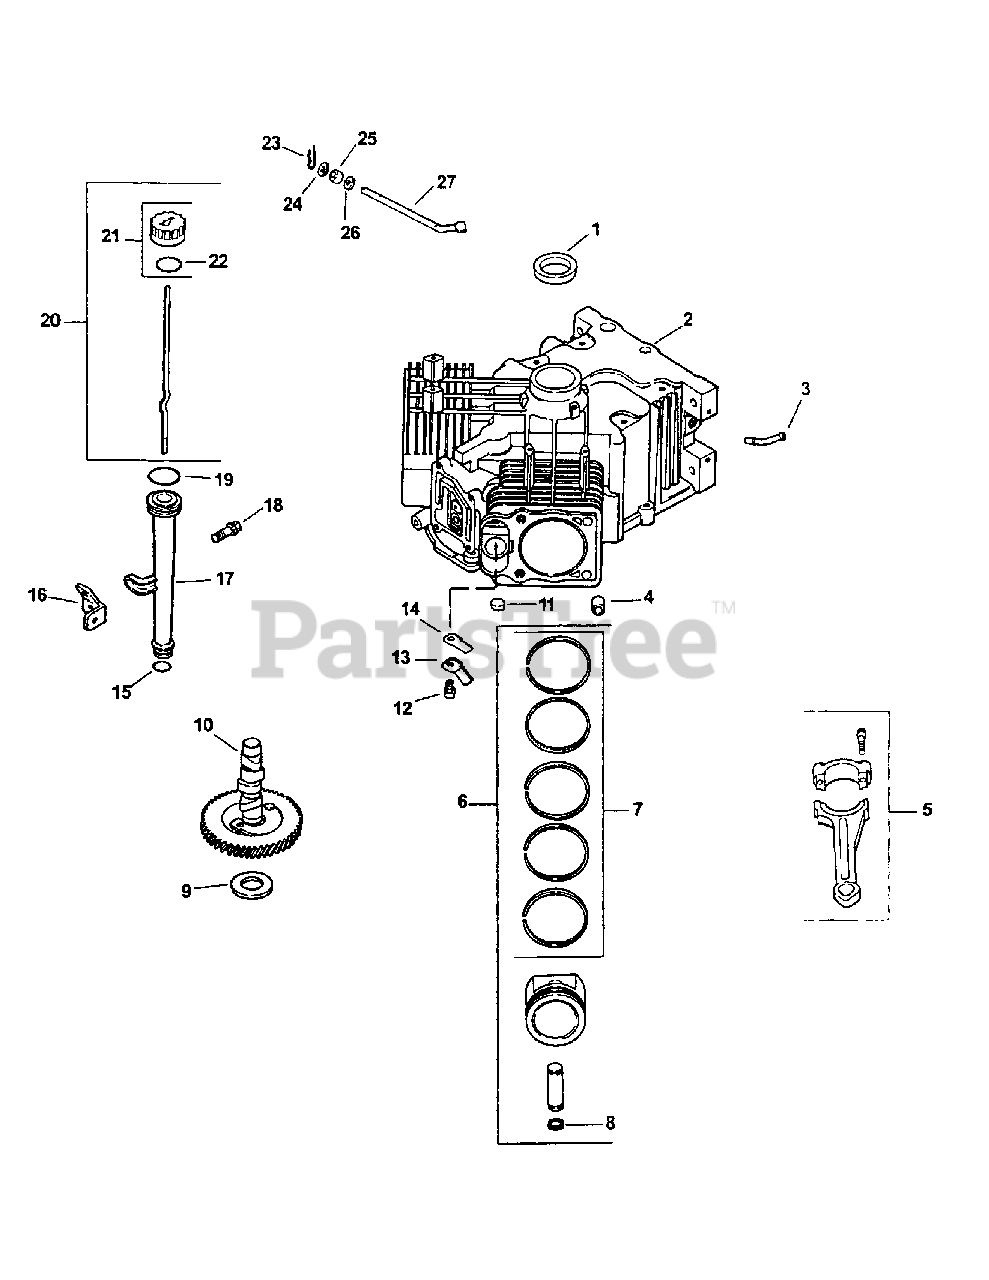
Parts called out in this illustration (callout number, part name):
1	Seal, Oil Front
2	Crankcase
4	Pin, Dowel Locating
5	Connecting Rod (Std.)
5	Connecting Rod (.25)
6	Piston w/Ring Set (Std.)
7	Ring Set (Std.)
8	Retainer, Piston Pin
9	Shim, Camshaft (A.R.) (White) .02725-.02875
9	Shim, Camshaft (A.R.) (Blue) .02925-.03075
9	Shim, Camshaft (A.R.) (Red) .03125-.03275
9	Shim, Camshaft (A.R.) (Yellow) .03325-.03475
9	Shim, Camshaft (A.R.) (Green) .03525-.03675
9	Shim, Camshaft (A.R.) (Gray) .03725-.03875
9	Shim, Camshaft (A.R.) (Black) .03925-.04075
10	Camshaft
11	Plug, Cup
12	Screw, Hex Flange
13	Retainer, Reed
14	Reed, Breather
15	O-Ring, Lower Oil Fill Tube
16	Bracket, Oil Fill Tube
17	Tube, Oil Fill
18	Screw, Hex Flange
19	O-Ring, Upper Oil Fill Tube
20	Dipstick Assembly
21	Kit, Oil Fill Cap
22	O-Ring, Dipstick
23	Pin, Hitch
24	Washer, Plain 6mm
25	Seal, Governor Cross Shaft
26	Washer, Plain 1/4"
27	Shaft, Governor Cross
